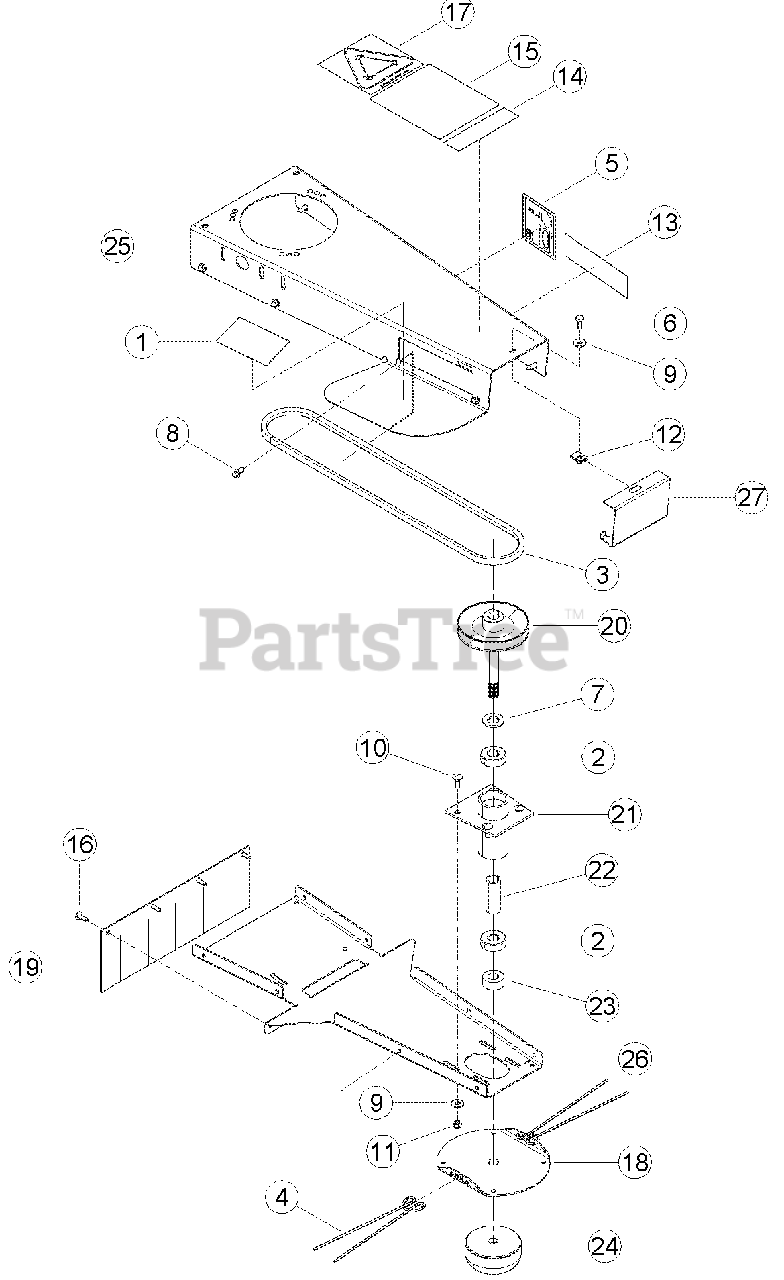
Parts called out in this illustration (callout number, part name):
1	DECAL, GRINDER DANGER
2	BEARING, 3/4 BALL
3	BELT, 4L 53 ARAMID
4	STRING, .155 X 20-1/2
5	DECAL, 101 DB
6	BOLT, 5/16 X 3/4 HEX HD GR5 ZP
7	WASHER, 3/4 SAE FLAT ZP
8	SCREW, 11/32 X 7/8 HWH AB THREAD ZP
9	WASHER, 5/16 FLAT ZP
10	BOLT, 5/16 X 7/8 CRG GR5 NC ZP
11	NUT, 5/16 NE NYLOCK ZP
12	NUT, 5/16-18 TINNERMAN U-TYPE
13	DECAL, ECHO BEARCAT 6.82 X 1.90
14	DECAL, MODEL WT190
15	DECAL, MANUAL/SAFETY INFO
16	RIVET, PLASTIC 1/4 X 7/8
17	DECAL, RECLAIM IT
18	DISK, TRIMMER HEAD
19	FLAP, TRIMMER
20	WELDMENT, TRIMMER PULLEY
21	WELDMENT, SPINDLE HUB
22	SPACER, TRIMMER SPINDLE
23	SPACER, TRIMMER HEAD
24	WELDMENT, TRIMMER HEAD USE 72704-12
25	BODY, TRIMMER
26	BOTTOM, TRIMMER FRAME
27	COVER, FRONT TRIMMER
